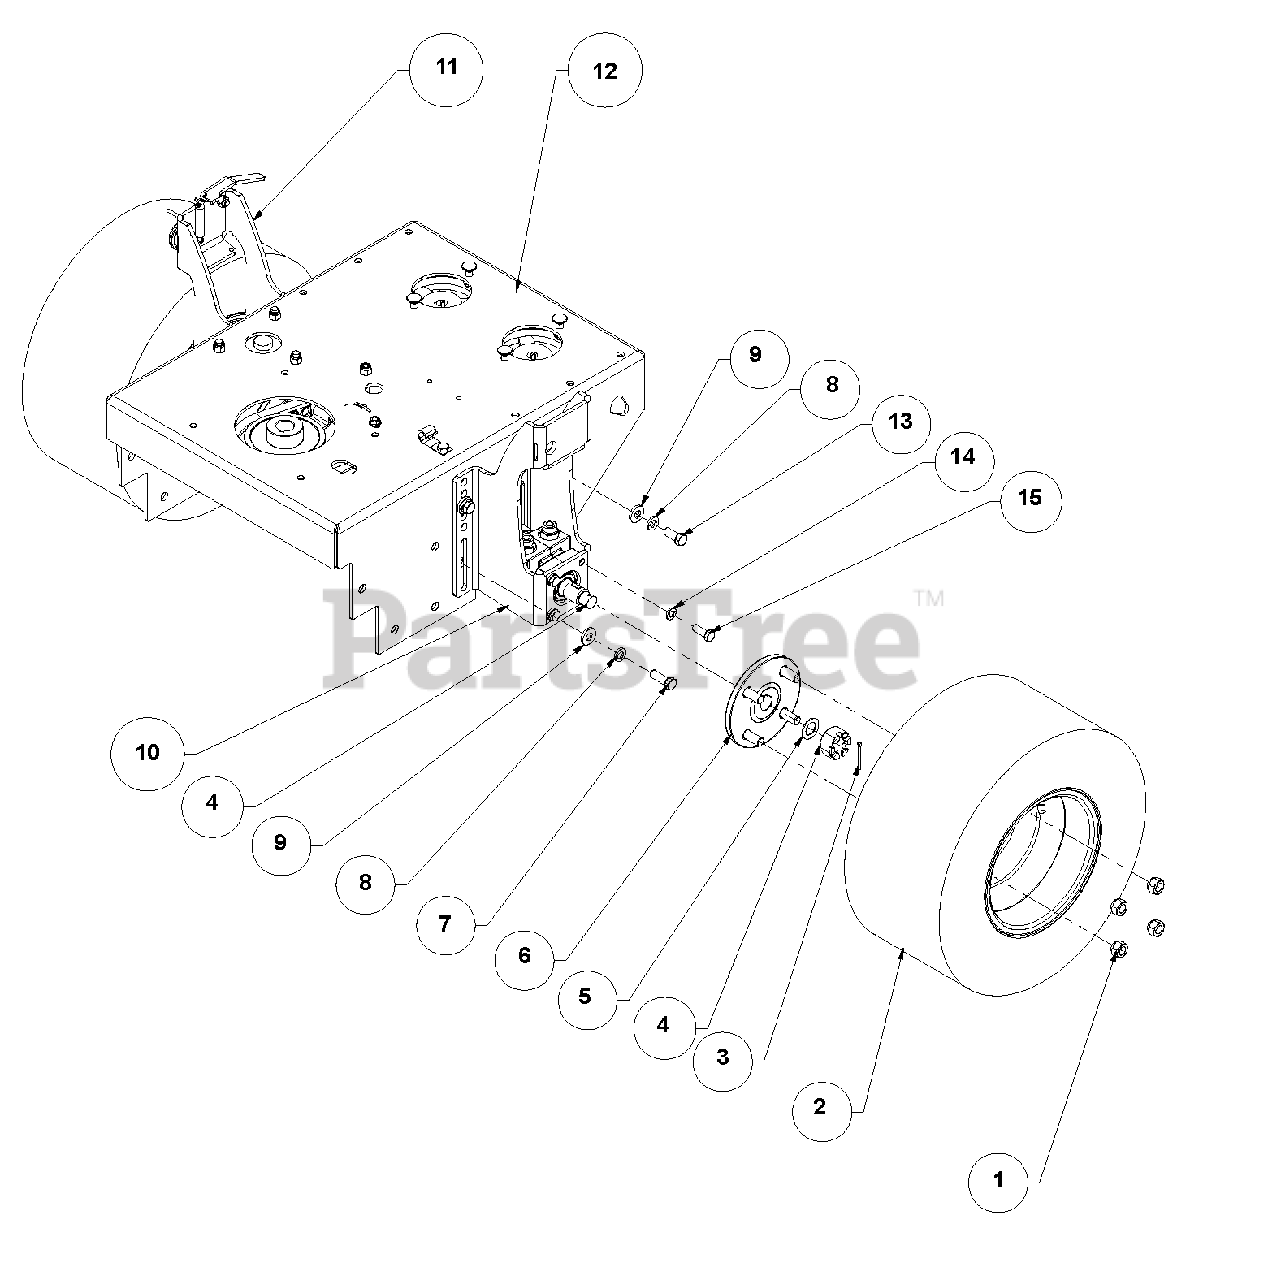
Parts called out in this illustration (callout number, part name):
1	Nut, .50-20 Lug
2	Assembly, Wheel and Tire-16 x 6.5-8
3	Pin, Cotter .125 x 1.50 EXTP
4	Motor, Hydraulic Wheel
5	Bushing, Machine .750 x 1.25 x .048
6	Assembly, Wheel Hub
7	Bolt, .4375-14 x 1.25 Hex 5
8	Washer, .438 Medium Spring Lock
9	Washer, .468 x 1.00 x .125 Flat
10	Bracket, Left Hand Combo WD Gravely (142)
11	Bracket, Right Hand Combo WD Gravely (142)
12	Weldment, Engine Plate TDF Gravely
13	Bolt, .4375-14 x 1.00 Hex 5
14	Washer, .375 Medium Spring Lock
15	Bolt, .38-16 x 1 Grade 8 Black
